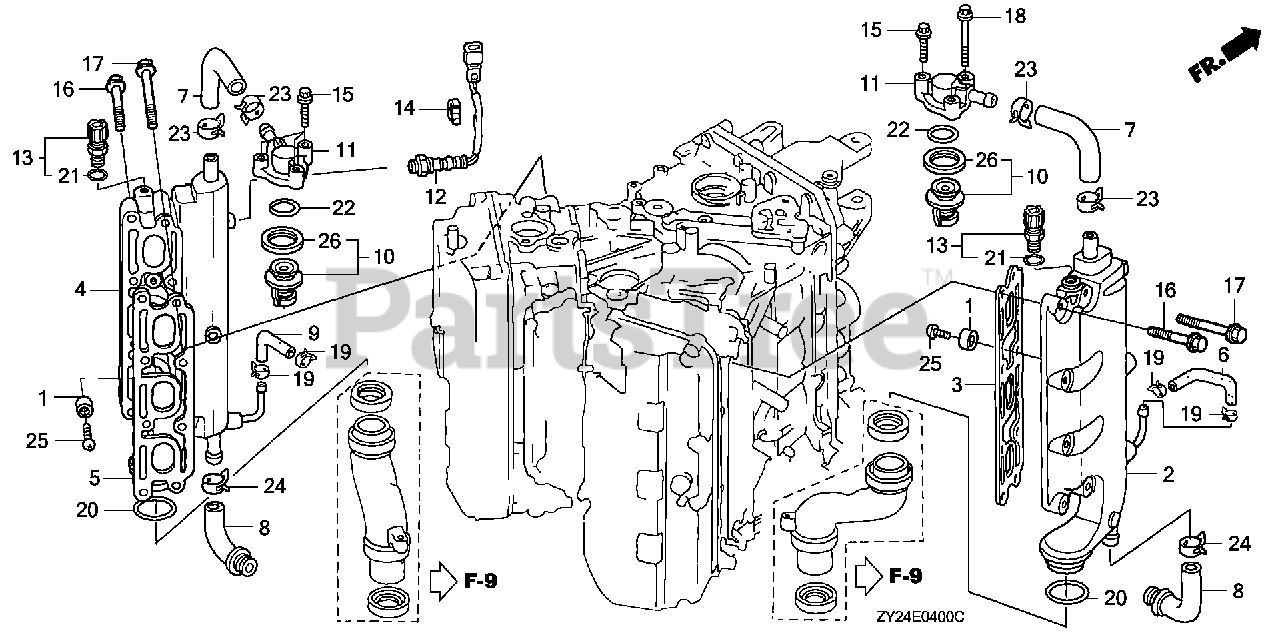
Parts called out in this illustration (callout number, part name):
1	METAL, ANODE
2	MANIFOLD, R. EX. *NH8* (DARK GRAY)
3	GASKET, R. EX. MANIFOLD
4	MANIFOLD, L. EX. *NH8* (DARK GRAY)
5	GASKET, L. EX. MANIFOLD
6	TUBE, R. WATER RETURN
7	TUBE, WATER RELIEF
8	TUBE, WATER
9	TUBE, L. WATER RETURN
10	THERMOSTAT ASSY.
11	COVER, THERMOSTAT *NH8* (DARK GRAY)
12	SENSOR, OXYGEN
13	SENSOR ASSY., WATER TEMPERATURE
14	CLIP, BRAKE PIPE (A) (FOR OXYGEN SENSOR)
15	BOLT, FLANGE (6X35)
16	BOLT, FLANGE (8X40)
17	BOLT, FLANGE (8X60)
18	BOLT, FLANGE (6X60)
19	CLAMP, TUBE (D10.5)
20	O-RING (66.4X3.1)
21	O-RING (9.5X1.9)
22	O-RING (31.5X2.4) (ARAI)
23	CLAMP, TUBE (D29)
24	CLAMP, TUBE (D21)
25	SCREW, PAN (6X18)
26	RUBBER, RING
